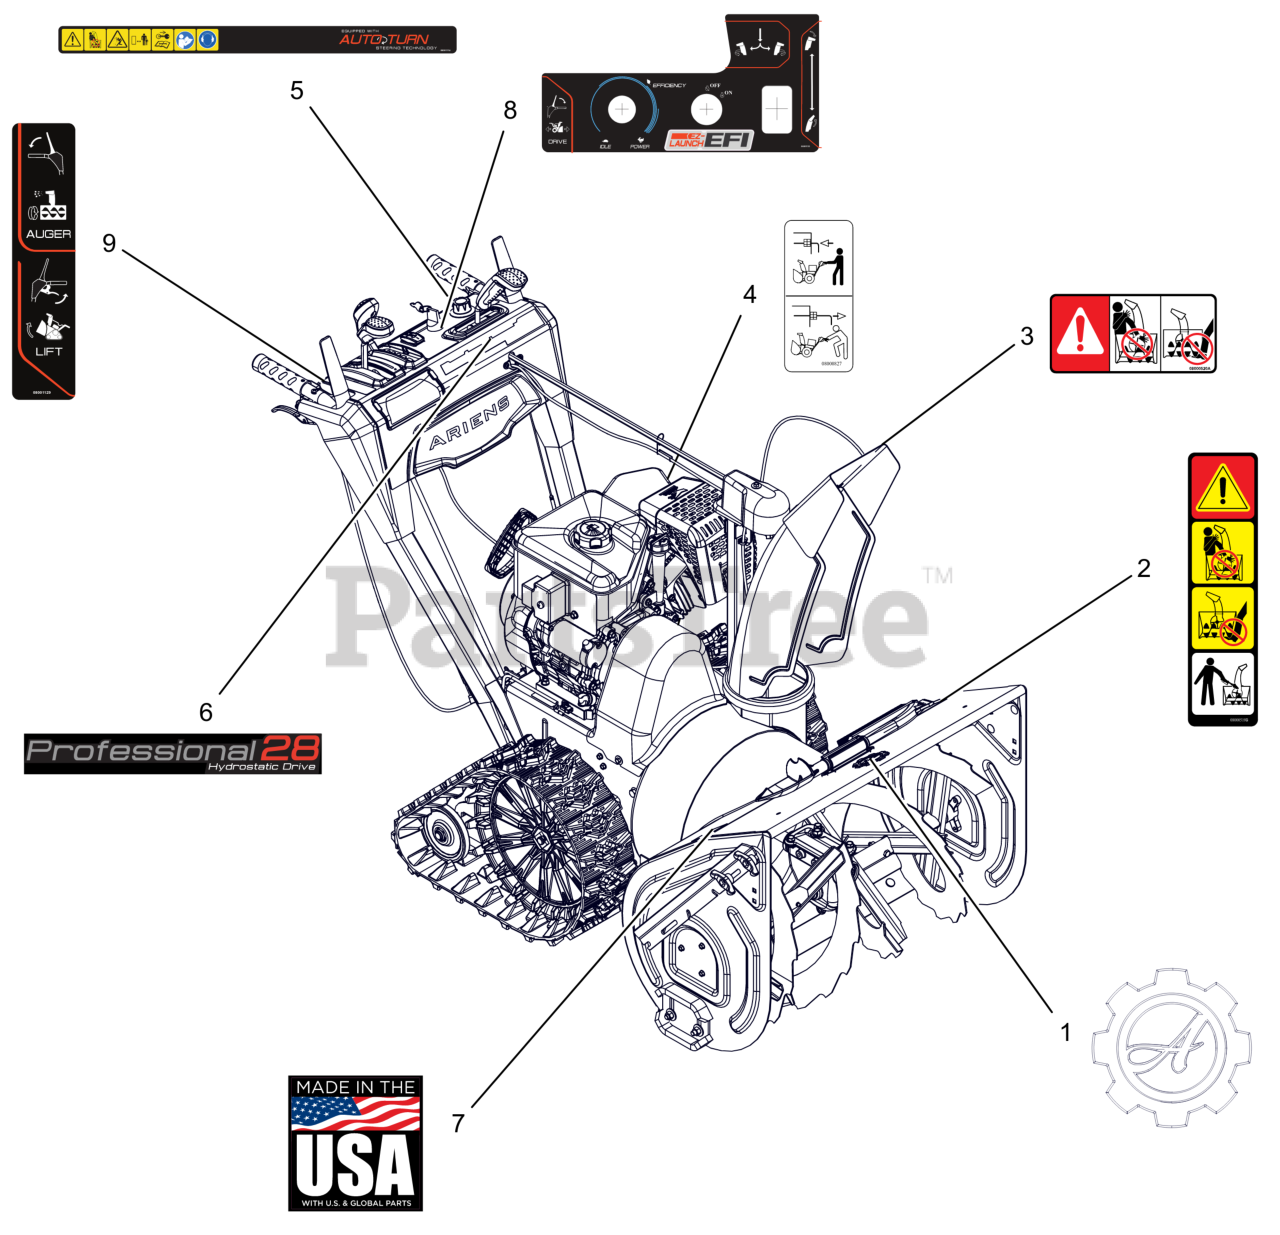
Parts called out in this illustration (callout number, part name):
1	DECAL, ARIENS-GEAR BADGE -THK
2	DECAL, DANGER - ROTATING PARTS
3	DECAL, DANGER
4	DECAL, BYPASS
5	DECAL,DASH - SAFETY/EFI
6	DECAL, DASH - PRO HYDRO 28
7	DECAL, MADE IN USA
8	DECAL, CONTROL - QT EFI W/GEL
9	DECAL,CONTROL-RH TRACK
